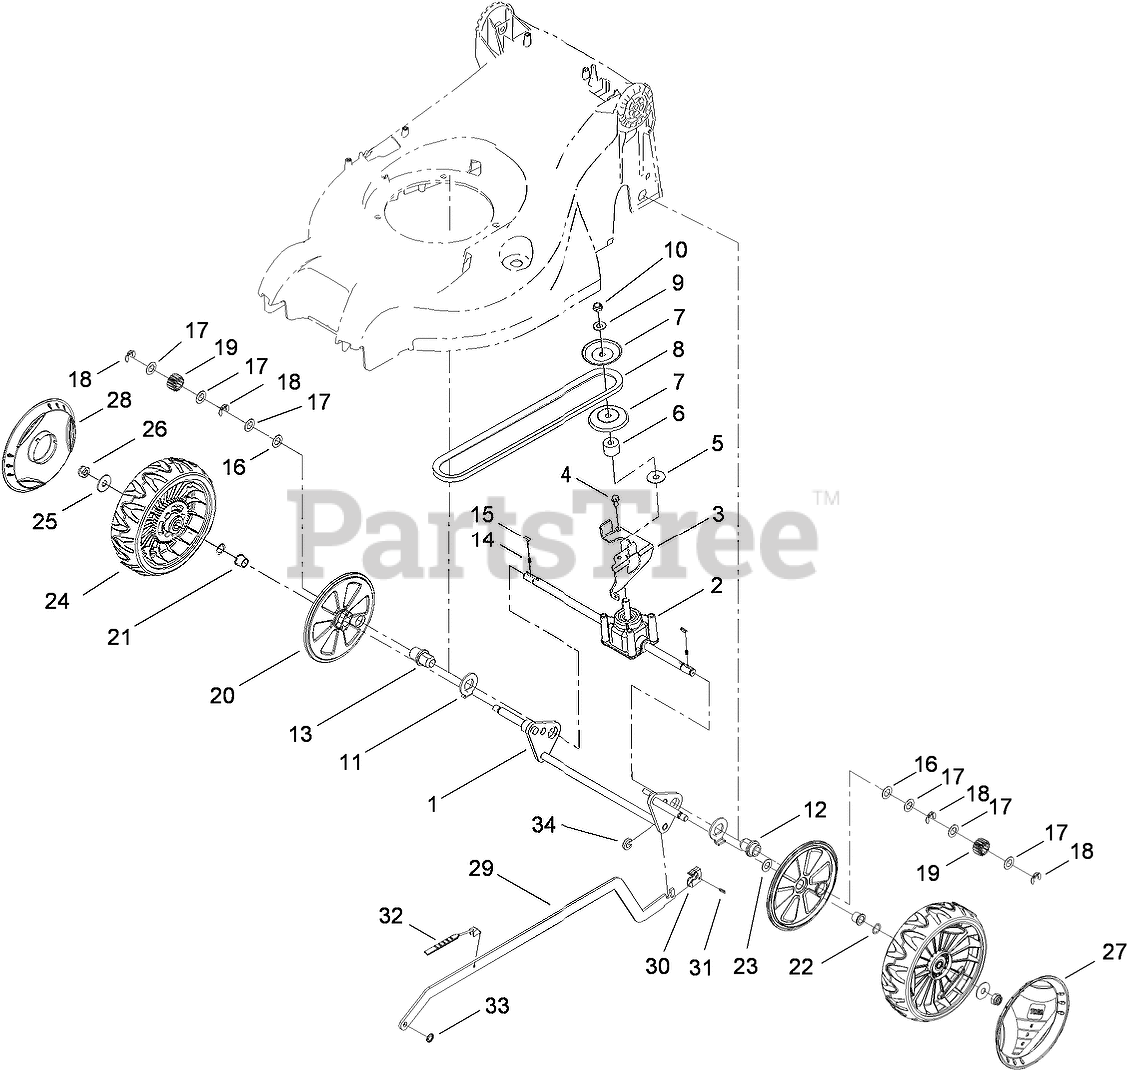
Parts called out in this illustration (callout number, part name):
1	PIVOT BAR ASM
2	TRANSMISSION ASM
3	BRACKET-CASE, GEAR
4	SCREW-HWH
5	WASHER-PLAIN
6	SPACER
7	PULLEY-HALF
8	V-BELT
9	WASHER-FLAT
10	NUT-HEX
11	CLIP-BUSHING
12	BUSHING-WHEEL, LEFT
13	BUSHING-WHEEL, RIGHT
14	SPRING-COMPRESSION
16	WASHER-PLAIN
17	Washer-Thrust
18	RING-CLIP, LOCKING
19	Gear-Pinion, 15t
20	COVER-WHEEL, INNER
21	HUB-AXLE, REAR
22	WASHER-SPRING
23	WASHER-PLAIN
24	REAR WHEEL ASM
25	WASHER-PLAIN
26	NUT-HH
27	COVER-WHEEL, SMART WHEEL
28	COVER-WHEEL, REAR
29	BAR-CONNECTION, HOC
30	CLIP-BAR, CONNECTION
31	PIN-GROOVE
32	SCALE-HOC
33	CLIP-PUSH
34	RING-FIXING
